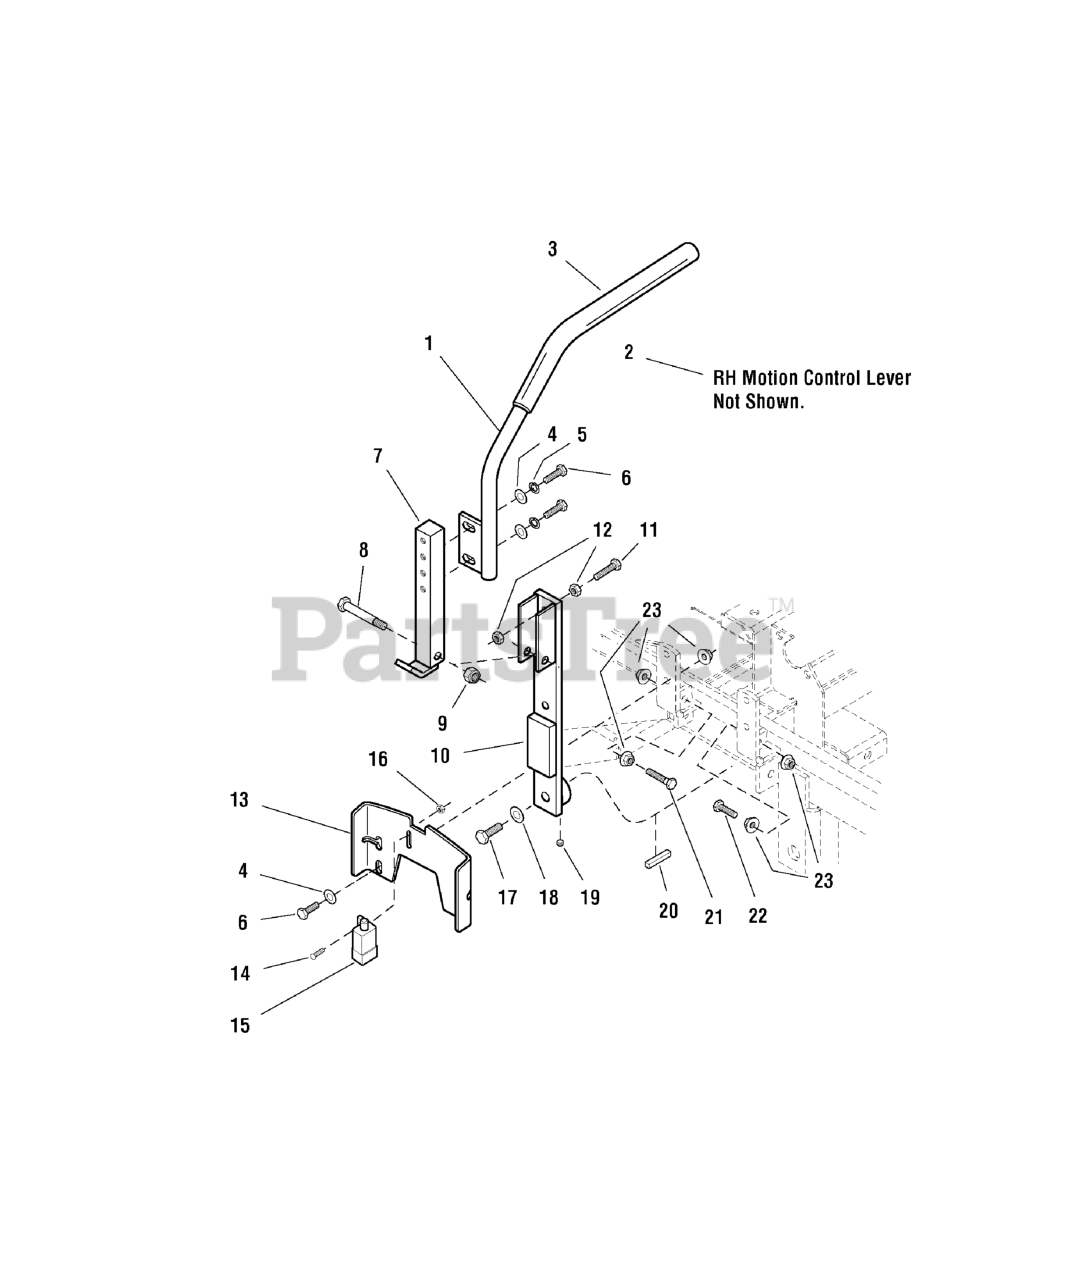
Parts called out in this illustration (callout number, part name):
1	MOTION CONTROL LEVER-RH
3	GRIP, Foam
4	WASHER, 5/16" SAE
5	WASHER, 5/16 LOCK CZ
6	BOLT, 5/16-18 X 3/4 GD5
7	WELD, CONTROL HANDLE BASE
8	BOLT, 3/8-16 X 2, GD5, CZ
9	NUT, 3/8-16 HEX NYLON LOCK
10	CONTROL LEVER MOUNT
11	BOLT, 5/16-18 X 1 GD5 YZ
12	NUT, 5/16-18 HEX
13	NEUTRAL LOCK PLATE
14	SCREW, #10-24 X 1 RS, CZ
15	SWITCH (see electrical group)
16	NUT, #10-24 Hex
17	BOLT, 3/8-16 x 1-1/4 w/ patch
18	WASHER, 3/8 SAE
19	SET SCREW, 5/16-18 x 1/4 w/ patch
20	KEY, 1/4 SQ. X 1
21	BOLT, 5/16-18 x 1-3/4
22	BOLT, 5/16-18 x 1-1/4
23	NUT, 5/16-18 HEX SERRATED FLANGE (SMALL)
